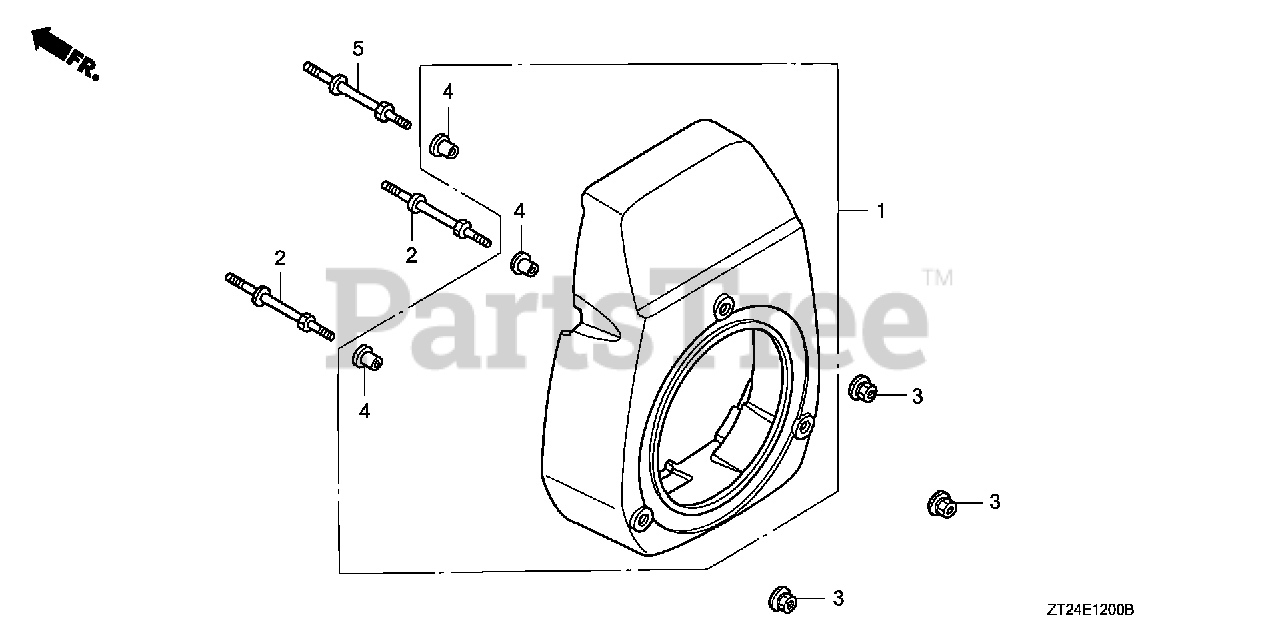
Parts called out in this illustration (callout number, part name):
1	COVER, FAN *NH1* (BLACK)
2	BOLT, STUD (H=42.5MM)
3	NUT, FLANGE (6MM)
4	COLLAR, FAN COVER
5	BOLT, STUD (H=42.5MM)
5	BOLT, STUD (H=39.5MM)
